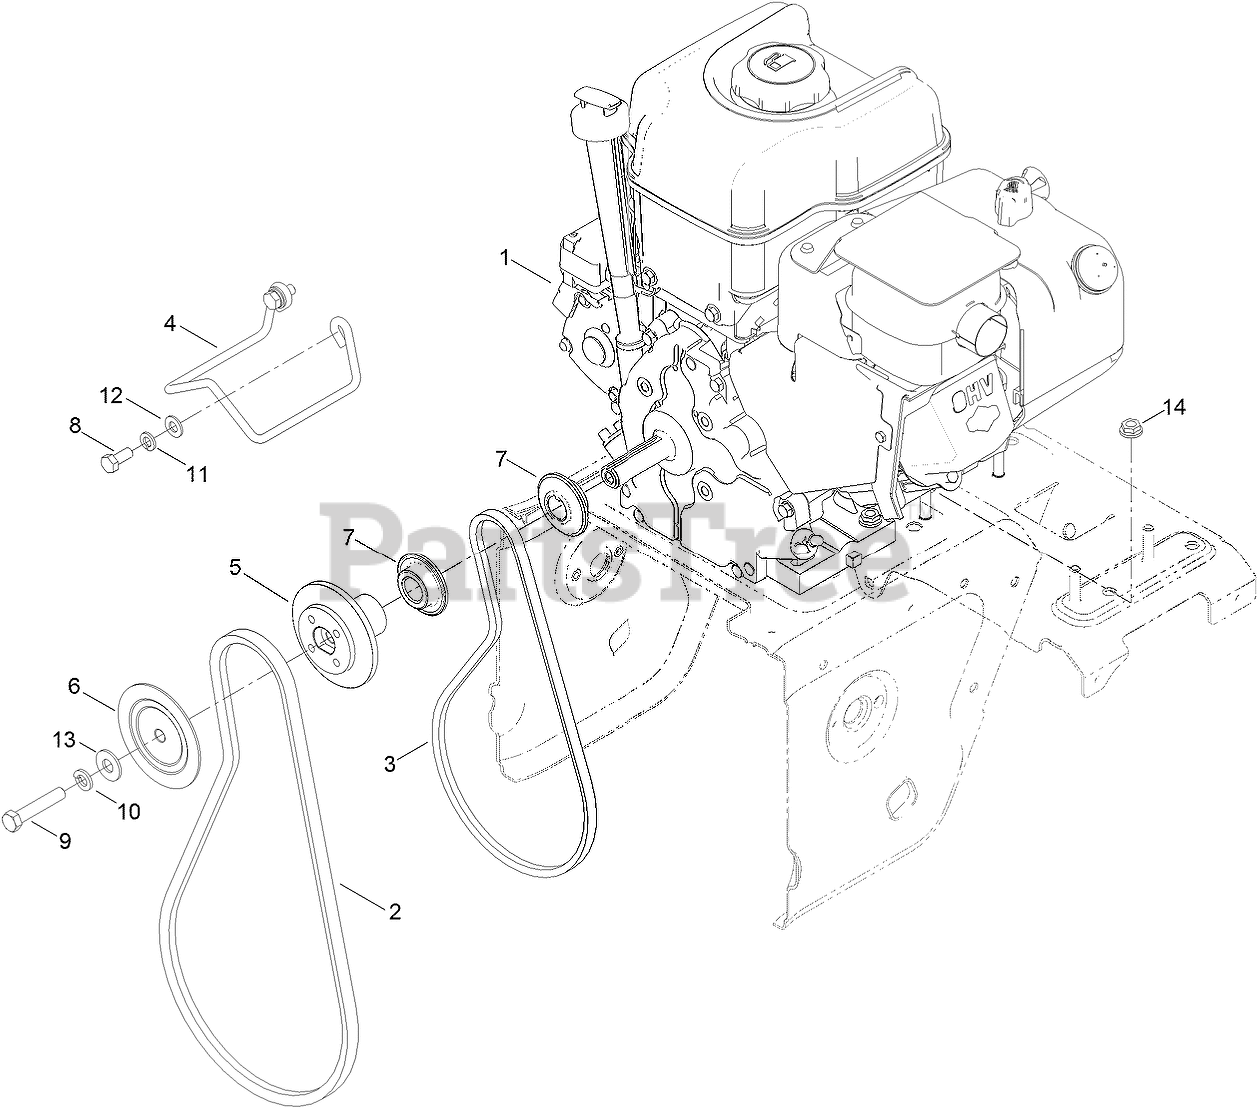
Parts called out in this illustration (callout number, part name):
2	BELT-V
3	BELT-V
4	GUIDE-BELT
5	PULLEY-AUGER, REAR
6	PULLEY-AUGER, FRONT
7	PULLEY-TRACTION
8	SCREW-HH
9	SCREW-HH
10	WASHER-LOCK
11	WASHER-LOCK
12	WASHER-PLAIN
13	WASHER-FLAT
14	NUT-HF
